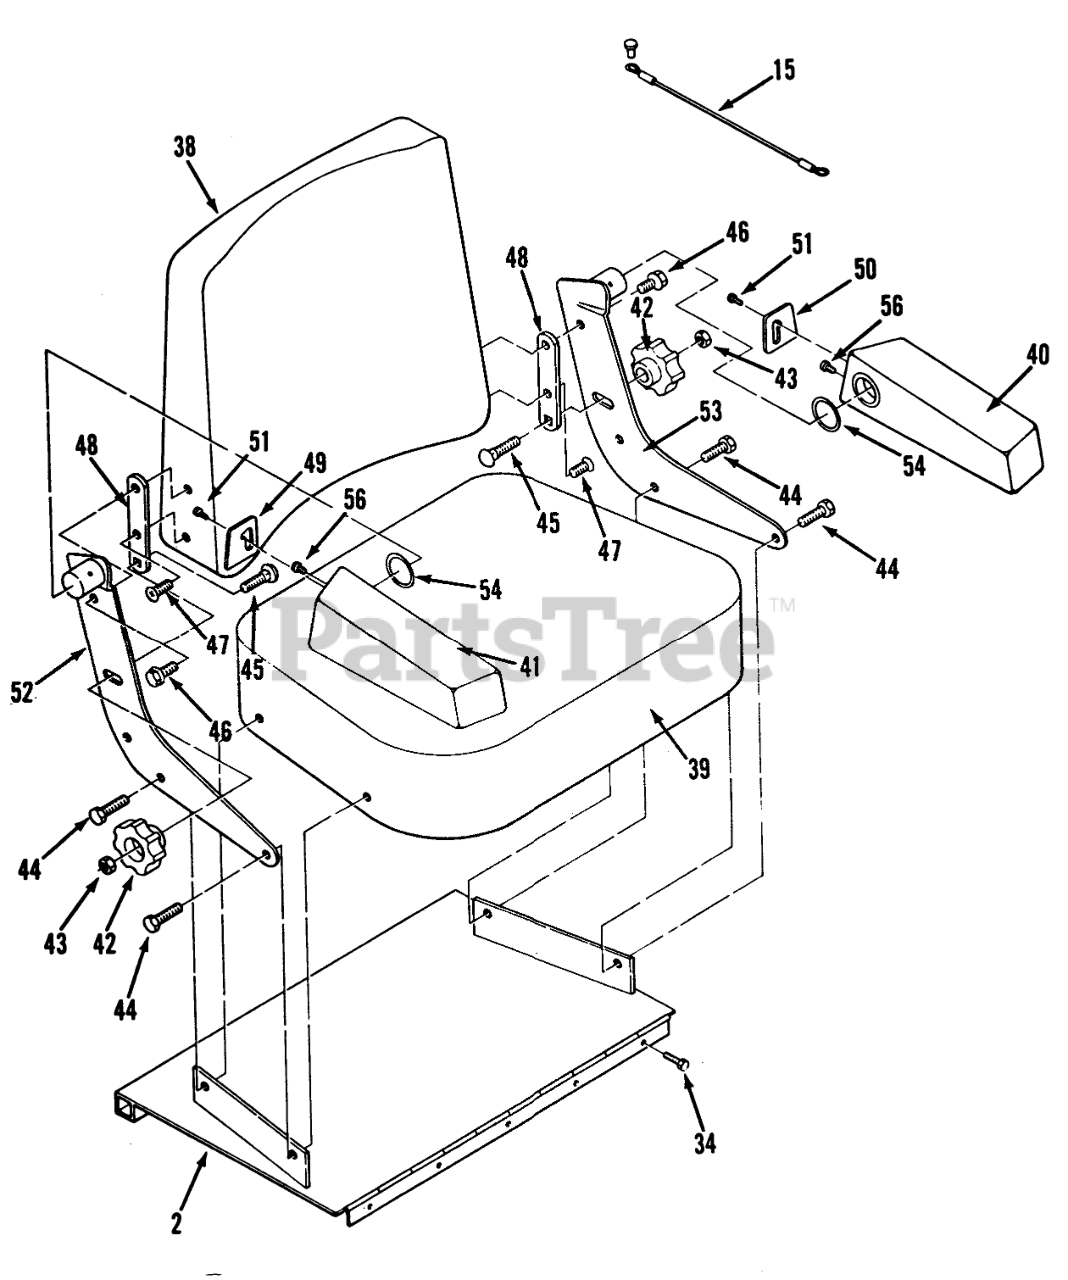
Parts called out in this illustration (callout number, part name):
2	Seat Mounting Bracket
15	Seat Cable
34	Bolt
38	Seat Back
39	Seat Bottom
40	ARM REST LH
41	ARM REST RH
42	Knob-Lumbar Control
43	LOCK NUT
44	Bolt
45	Bolt
47	Screw-Phillips Hd
48	Lumbar Friction Plate
49	ARM REST PLATE RH
50	ARM REST PLATE LH
51	SCREW PAN HD 10-16X5
52	BACK SUPT LH
53	Back Support LH
54	WASHER
56	SHCS 1/4-20 X 1/2
